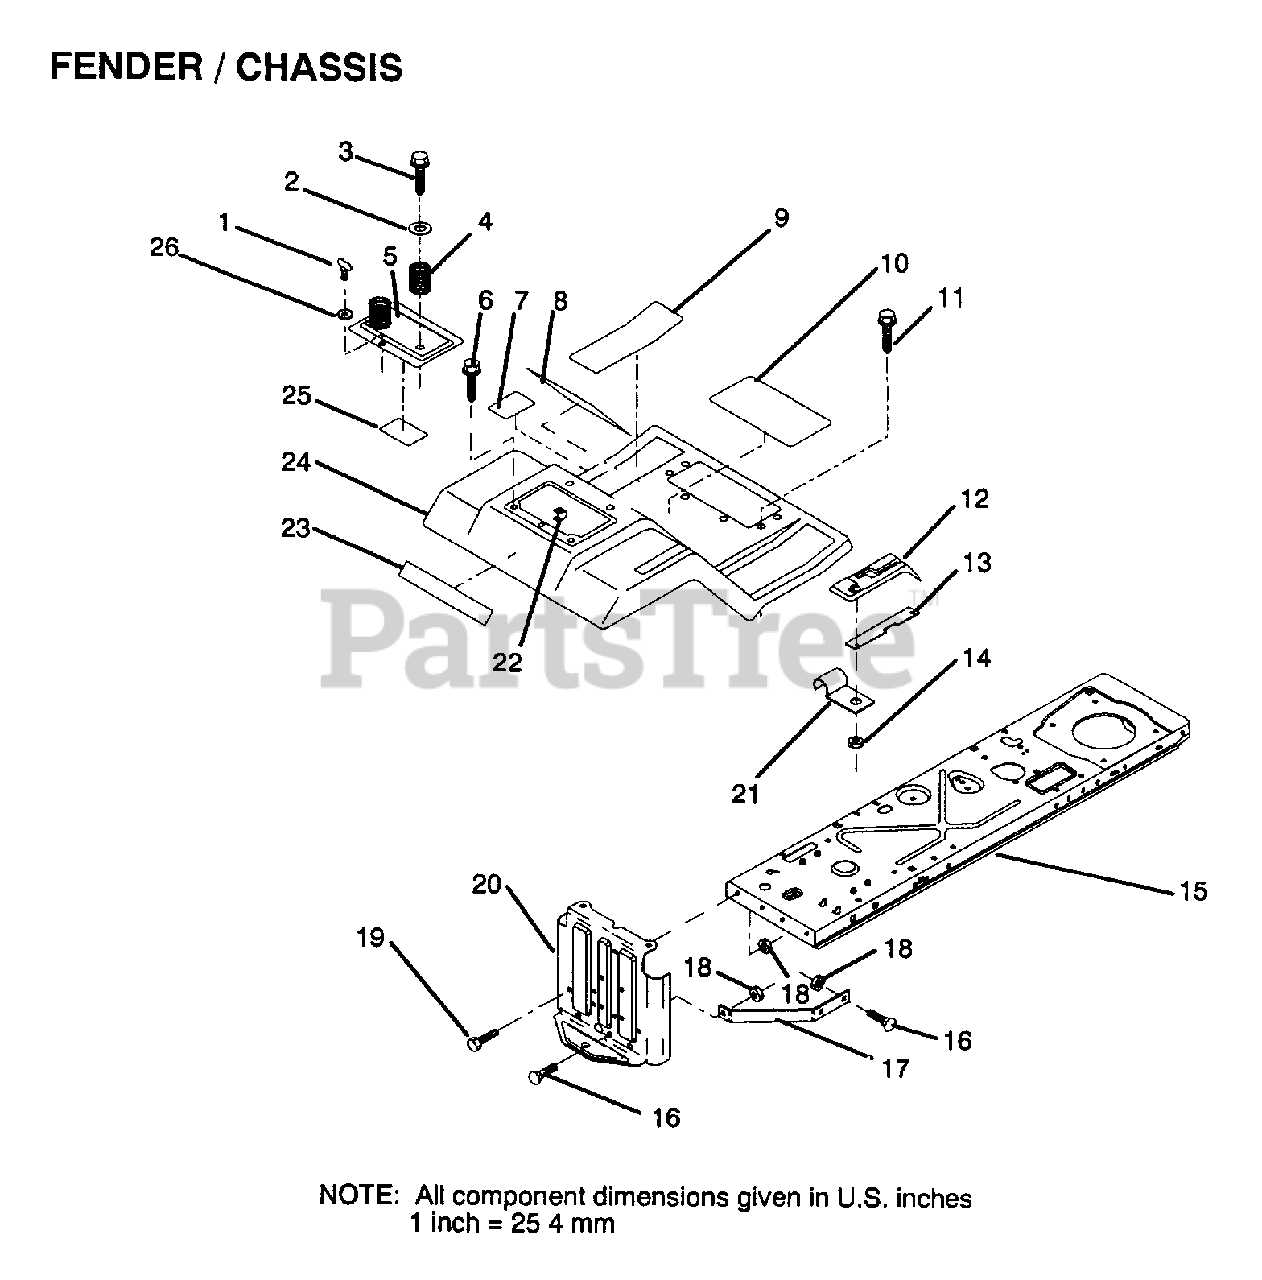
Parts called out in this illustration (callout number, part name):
1	STUD.1/4.TURN
2	WASHER
3	SCREW
4	SPRING COMPRESSIO
5	"DOOR,FENDER T"
6	SCREW LT
7	DECAL DRIVE
8	DECAL
9	PAD FOOTREST
11	SCREW
13	"SHIFT LOCK, BAR"
14	NUT
15	FRAME ASS'Y
16	BOLT
17	"BRACE,DRAWBAR "
19	BOLT
20	DRAWBAR
21	"CLIP,INSULATOR"
22	RECEPTACLE LT
23	"DECAL,FENDER"
24	"FENDER,FOOTREST T"
25	DECAL
26	RETAINER LT
